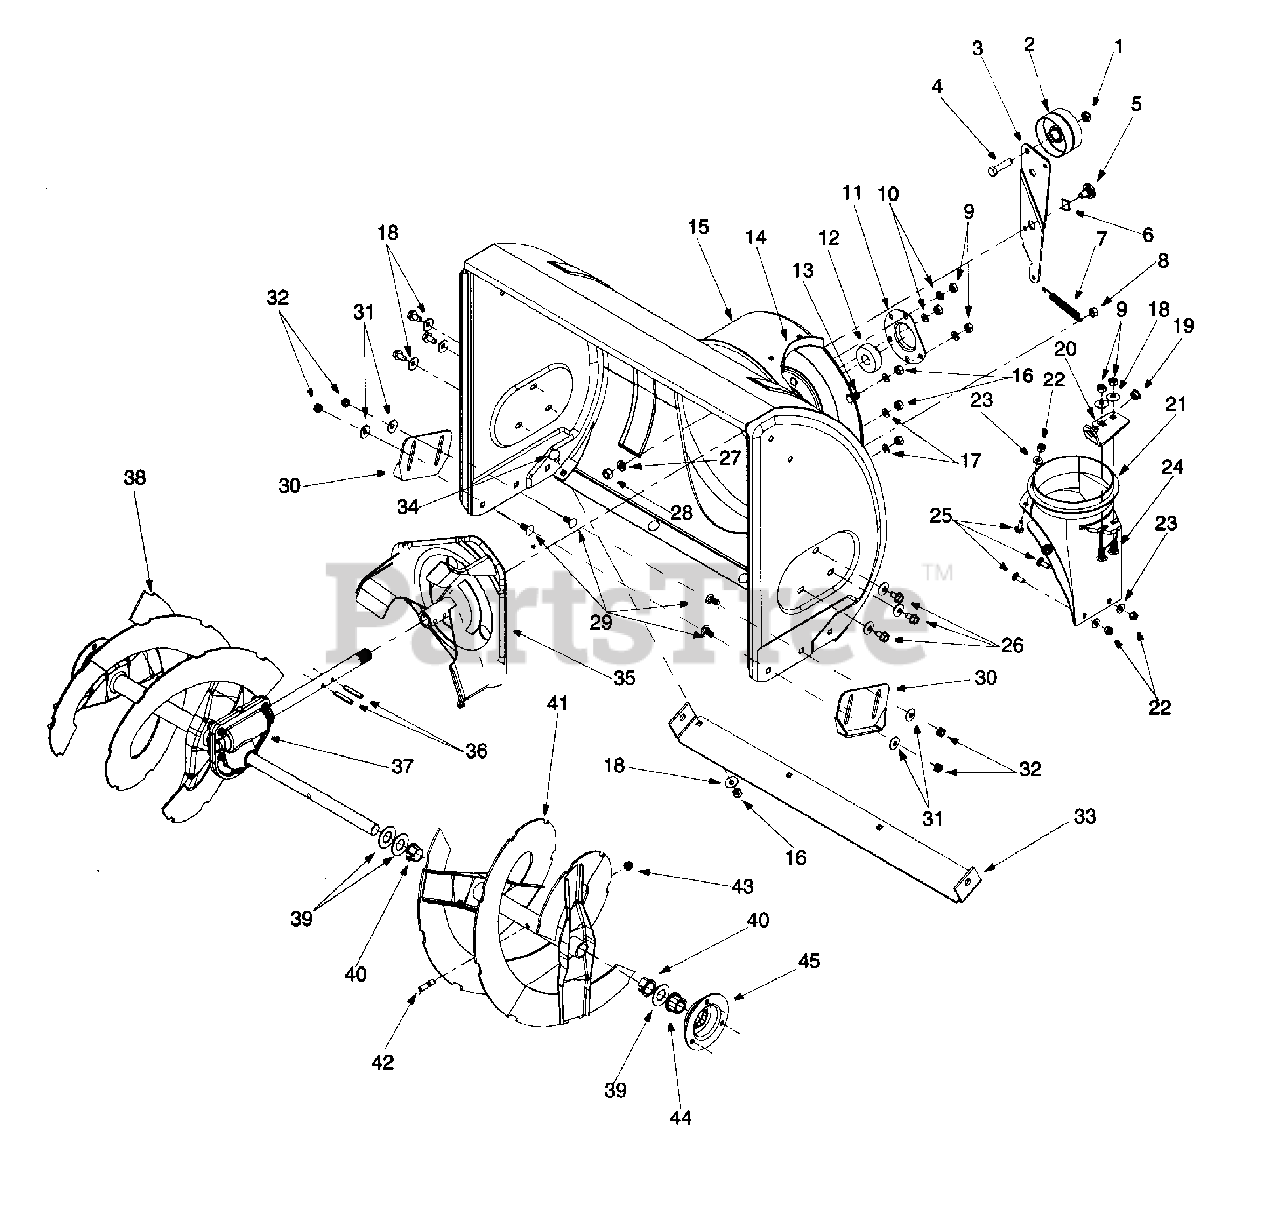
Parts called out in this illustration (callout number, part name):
1	Lock Jam Nut 3/8-24
2	Flat Idler
4	Hex Cap Screw 3/8-24 x 1.50
5	Shoulder Screw
6	Wave Washer
7	Extension Spring
8	Hex Nut 5/16-18
9	Hex Nut 5/16-18
10	Lock Washer 5/16
11	Housing
12	Ball Bearing
13	Carriage Bolt 5/16-18
17	Lock Washer 5/16
18	Bell Washer
19	Bushing
21	Chute Adapter
22	Hex Lock Nut 1/4-20
23	Flat Washer
24	Carriage Bolt
25	Carriage Screw 1/4-20 x .75
26	Hex Washer Screw 5/16-18
27	Lock Washer 3/8
28	Hex Nut 3/8-16
29	Carriage Bolt 5/16-18 x .75
31	Bell Washer
32	Hex Nut 5/16-18
34	Carriage Bolt 5/16-18 x .62
37	26" Gear Assembly
39	Flat Washer
40	Flange Bushing
43	Lock Nut 5/16-18
44	Hex Flange Bearing
